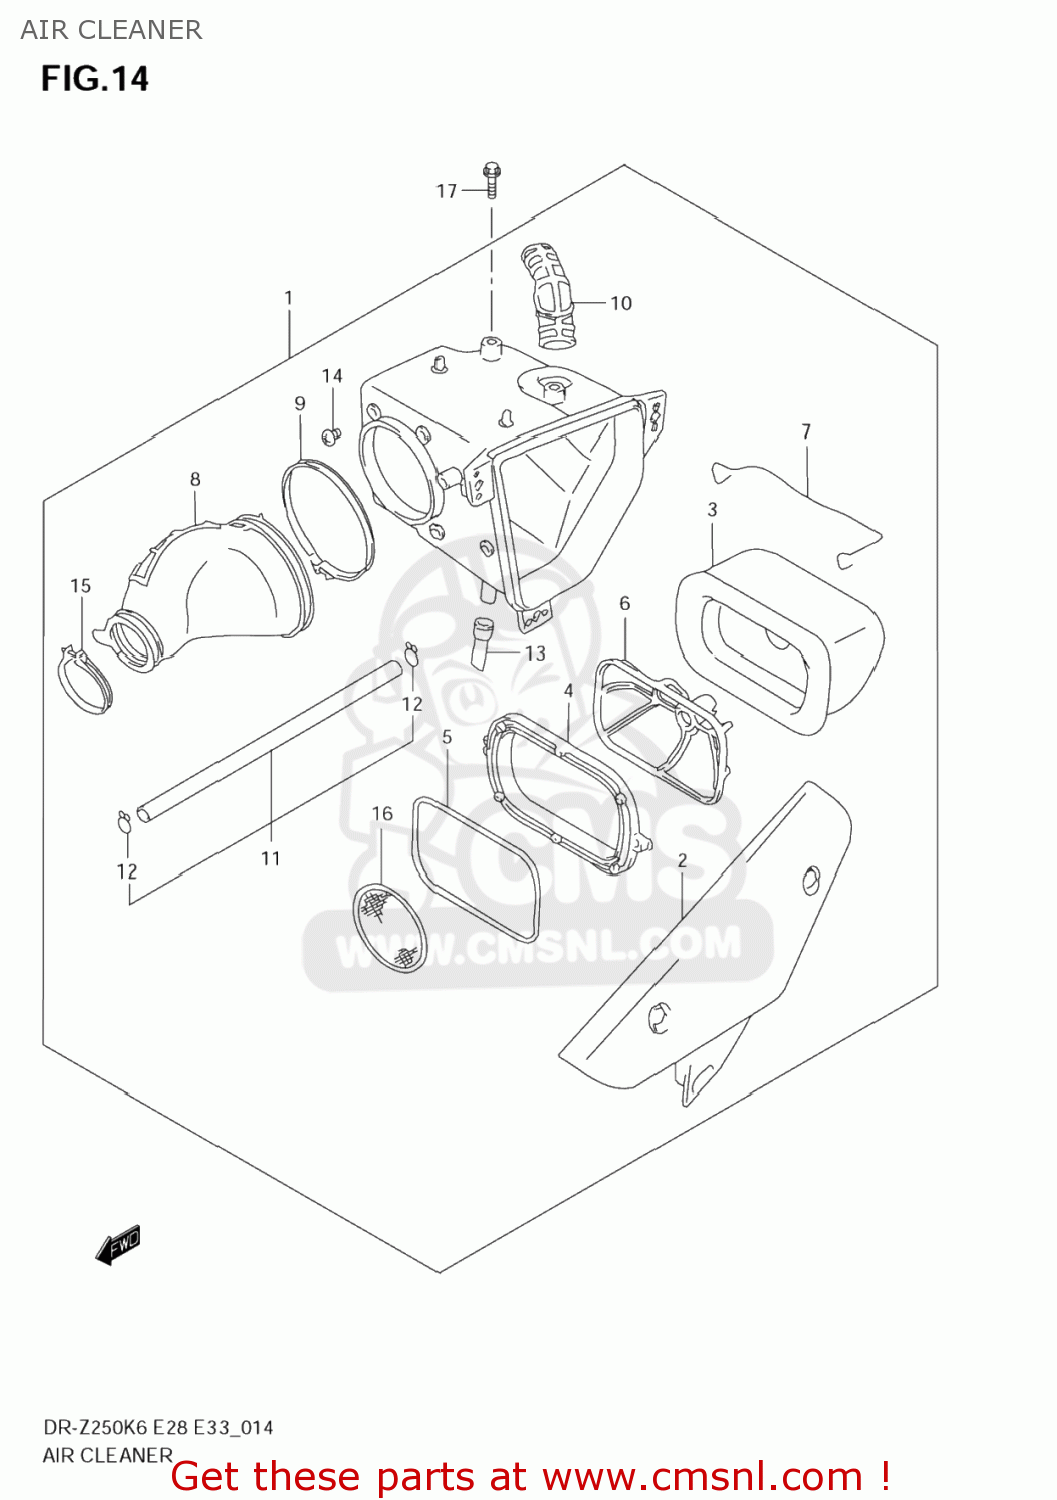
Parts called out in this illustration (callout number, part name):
1	CLEANER ASSY,AIR
2	CAP,CLEANER
3	FILTER,CLEANER
4	BASE,FILTER
5	GASKET
6	HOLDER,FILTER
7	SPRING
8	TUBE,OUTLET
9	CLAMP
10	TUBE,INLET
11	TUBE,BREATHER
12	CLIP
13	CAP,DRAIN
14	SCREW
15	CLAMP
16	TRAP,FRAME
17	BOLT
